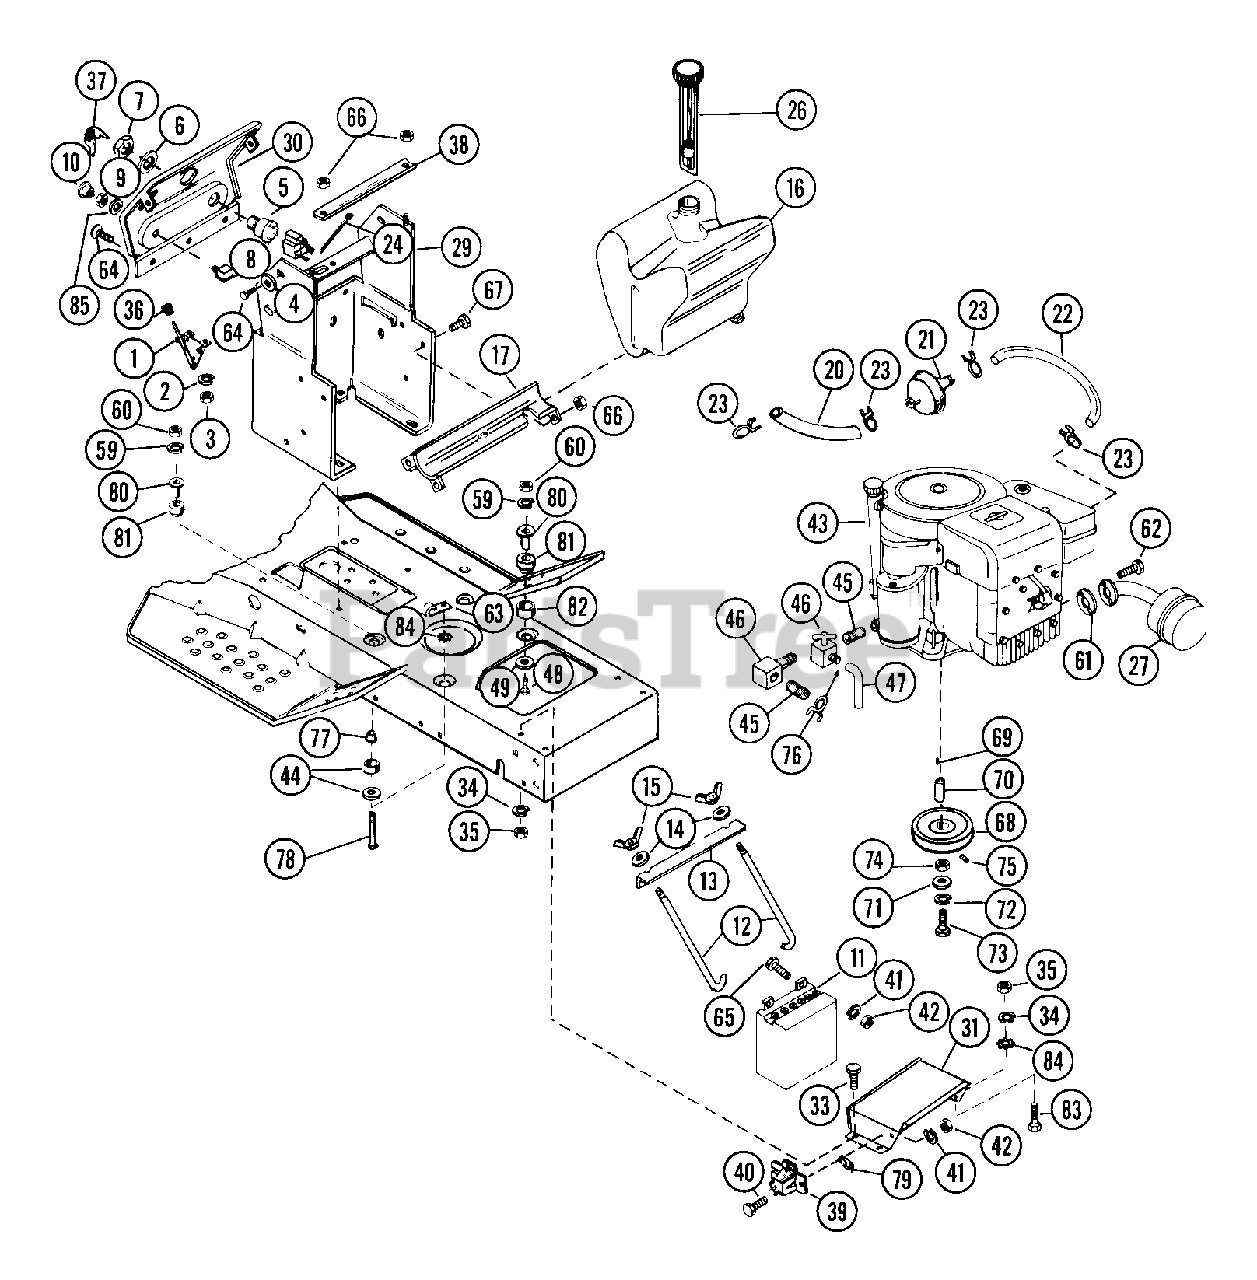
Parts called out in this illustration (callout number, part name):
1	THROTTLE CONTROL
2	WSHR-LK 10X.047 MED PL
3	NUT-HEX 10-24 PL
4	WSHR-FL-STL .250X.562X.049 PL
5	IGNITION SWITCH
6	WSHR-LK-INT .563X.040 PL
7	NUT .562-24
8	LIGHT SWITCH
9	NUT .50-20 PL
11	BATTERY
12	HOOK BOLT
13	BATTERY HOLD DOWN
14	WSHR-FL-STL.312X.734X.065PL
15	NUT-WING .250-20 YWZC
16	FUEL TANK
17	LOWER TANK SUPPORT
20	HOSE (SERV. ONLY)
21	FUEL FILTER
22	HOSE (SERV. ONLY)
23	CLAMP-HOSE WIR.490/.510X.092#8
24	TIE DOWN
25	GROUND CABLE .31X22.00X.31
26	FUEL GAUGE
27	EXHAUST MUFFLER
29	DASH BASE WITH DECALS
30	DASH
31	BATTERY STAND
32	FRAME W/DECALS
33	BLT-HEX .31-18X.50 PL GR2
34	WSHR-LK .312X.097 PL HVY
35	NUT-HEX .312-18
37	KEYS
38	CLAMP STRAP
39	SOLENOID
40	BLT-HEX .25-20X.75 PL GR2
41	WSHR-LK .250X.077 HVY PL
42	NUT-HEX .250-20 PL
43	8 H.P. TECUMSEH ENGINE 35SERIE
44	TOP ISOLATION MOUNT
45	BUSHING
46	DRAIN LOCK
46	PIPE FITTING 90 DEG. X 3/8 ELB
47	HOSE (SERV. ONLY)
48	BLT-HEX .31-18X2.00 PL GR5
48	BLT-HEX .31-18X2.50 PL GR2
49	WSHR-FL-STL .312X1.62X.13
59	WSHR-FL-STL.312X.734X.065PL
59	WSHR-LK .312X.097 PL HVY
60	NUT-LK-TOP .312-18 GR C PL
60	NUT-HEX .312-18
61	GASKET - EXHAUST FLANGE
62	SCR-SKH .31-18X.75 PL
63	J-CLAMP
64	SCR-SHT.MET10-16X.375 HWH PL B
65	BLT-HEX .25-20X.75 PL GR2
66	NUT-LK TOP .250-20 PL
67	BLT-HEX .25-20X.50 PL GR2
68	PLY-? 3.50X1.0
69	KEY-SQ .25X1.0X.25 SAE 8630
70	BEARING SPACER 1.032X1.25X1.78
71	WSHR-FL-STL .469X1.380X.125
72	WSHR-LK .438X.133 HVY
73	BLT-HEX .44-20X1.00 GR5
74	SPACER 1.032X1.250X.312
75	SCR-SET .32-18X.25 SKHCUP OH
76	HOSE CLAMP
77	RUBBER BUSHING
80	SPACER-SHOULDER
81	BOTTOM ISOLATION MOUNT
82	ENGINE SPACER
83	BLT-HEX .31-18X.75 PL GR2
84	WSHR-LK-EXT .313X.030 PL
85	WSHR-FL-STL .382X.812X.023 PL
86	BLT-HEX .31-18X2.75 PL GR2
86	WSHR-LK .312X.097 PL HVY
86	NUT-JAM .312-24 PL
86	WSHR-LK 10X.047 MED PL
86	NUT 10-32 PL
